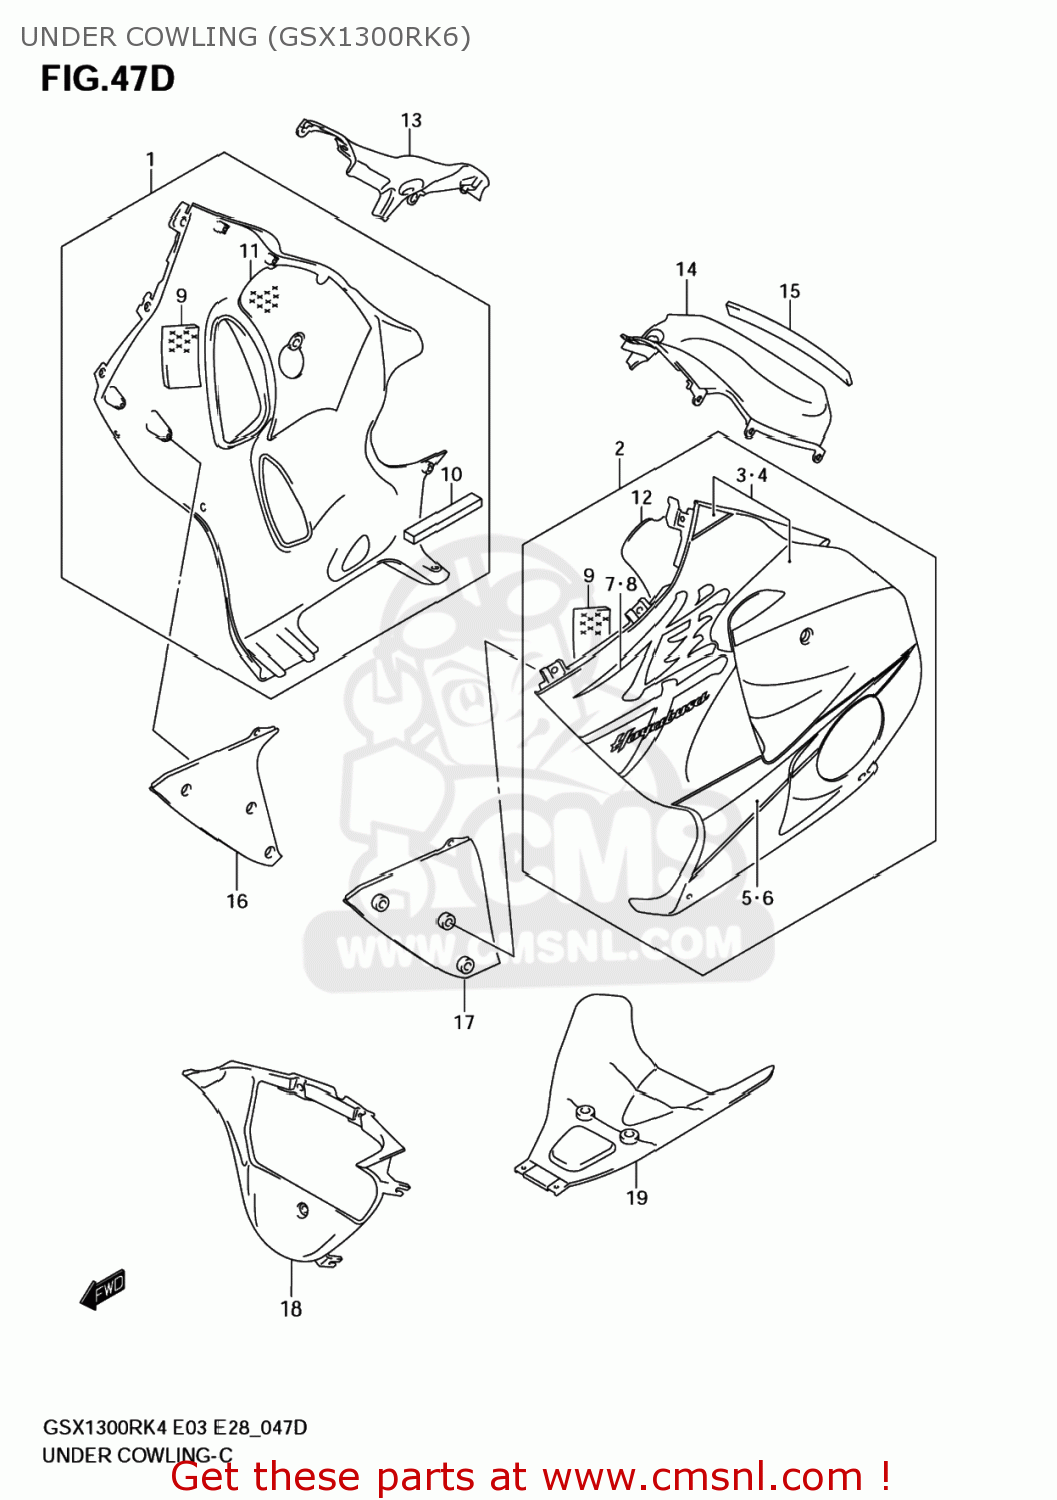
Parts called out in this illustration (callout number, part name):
1	COWL ASSY,UNDE
2	COWLING ASSY,U
3	TAPE SET,UNDER UPR,R
4	TAPE SET,UNDER UPR,L
5	TAPE,UNDER LOW
6	TAPE,UNDER LOW
7	EMBLEM,COWLING UNDER,R
8	EMBLEM,UNDER,L
9	CUSHION,UNDER COWLING NO,1
10	CUSHION,ENGINE COVER,RIGHT
11	CUSHION,UNDER COWLING NO.2,R
12	CUSHION,UNDER COWLING,L
13	PANEL,SIDE,R
14	PANEL,SIDE,L
15	MOLDING,SIDE PANEL
16	COWLING,UNDER INNER,R
17	COWLING,UNDER INNER,L
18	COWLING,UNDER CTR
19	COWLING,UNDER RR
